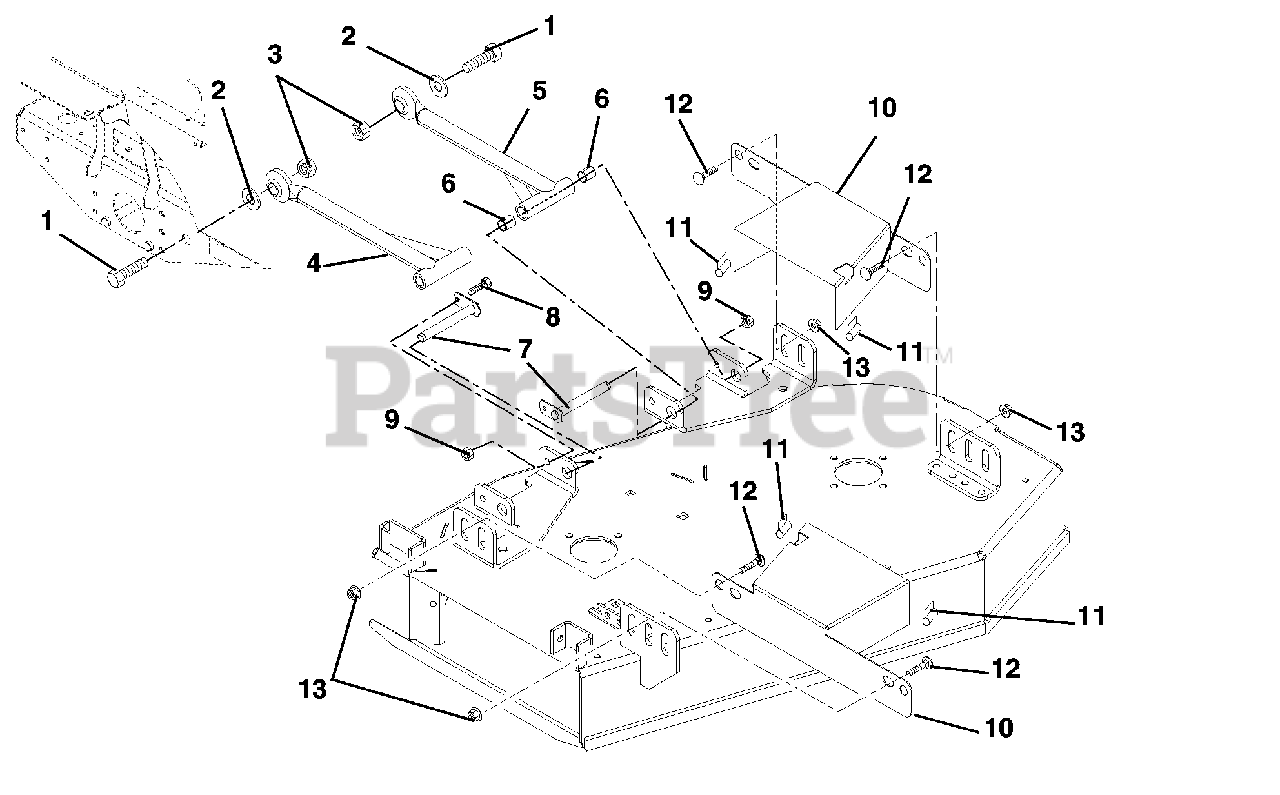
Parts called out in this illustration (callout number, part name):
1	Bolt, Hex .875-9 x 3.00
2	Bushing, Sleeve .875 x 1.25 x .531
3	Nut, Locking Center .875-9
4	Assembly, Mower Mounting
5	Arm, Mower Mounting
6	Bearing, .75 x .875 x 1.00
7	Weldment, Mower Mounting Pin
8	Bolt, Hex .38-16 x 1.00 Grade 5
9	Nut, Locking Top Flange .38-16
10	Guard, 34" Belt
11	Seal, Trim-LOK Bulk .06 Bubble
12	Bolt, Round Head Square Neck .50-13 x 1.00 Grade 5
13	Nut, Locking Top Flange .50-13
